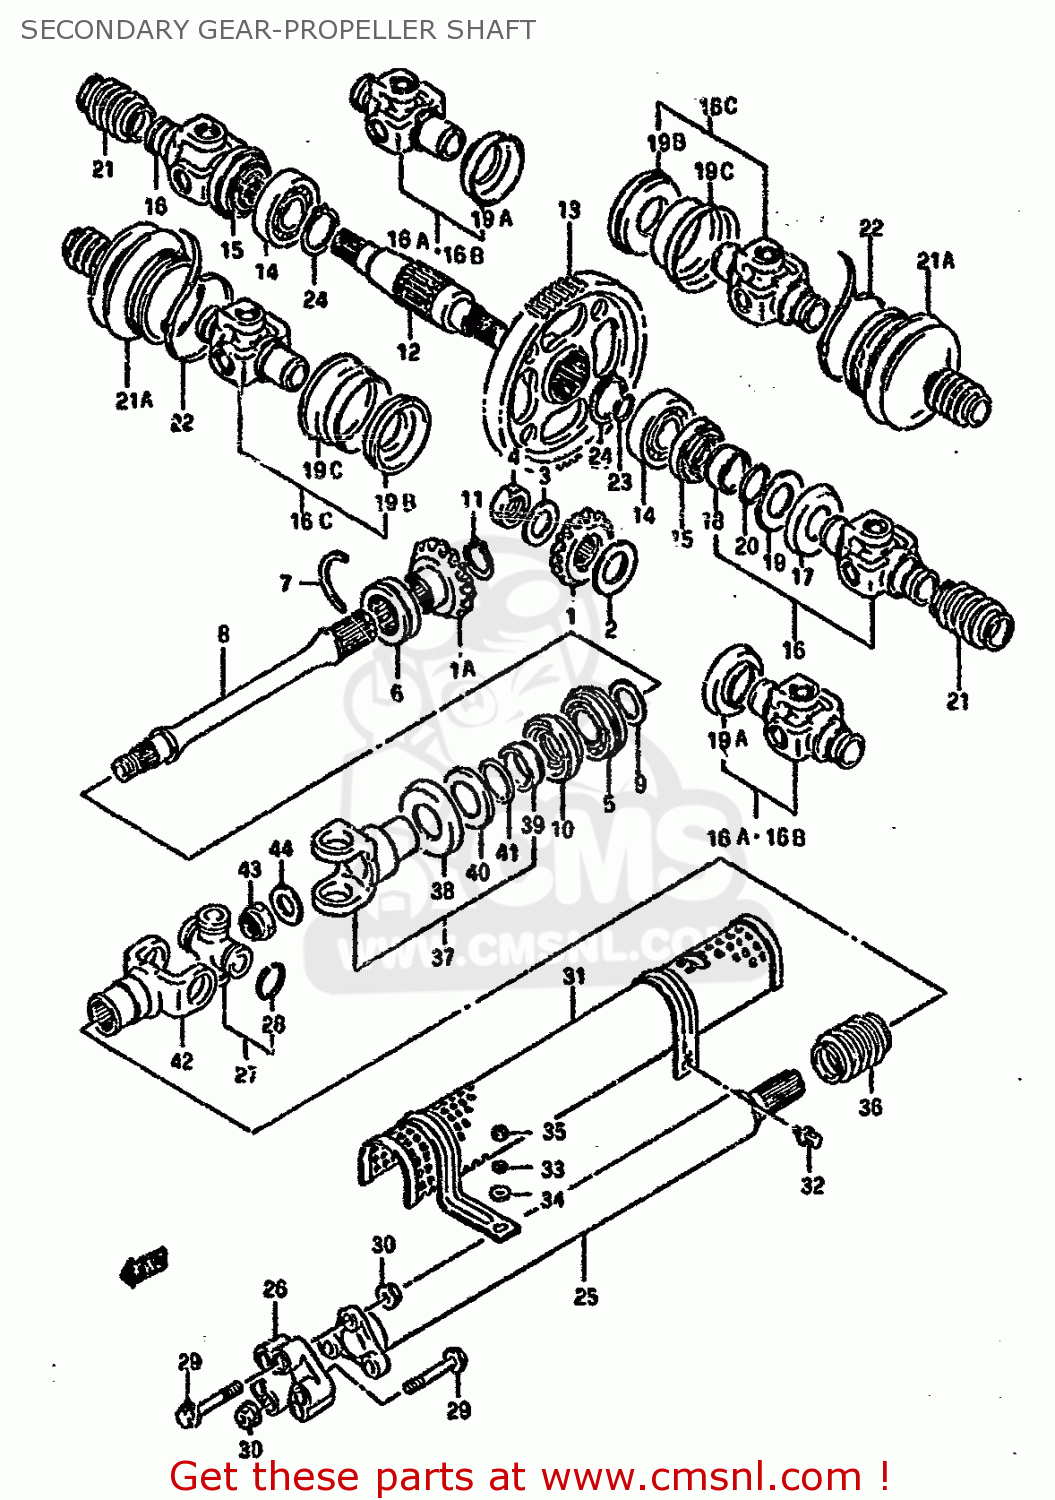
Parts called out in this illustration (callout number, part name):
1	GEAR,SECONDARY DRIVE BEVEL
1A	GEAR,2NDRY DRIVEN BEVEL
2	SHIM,SECONDARY DRIVE
3	WASHER
4	NUT
5	BALL BEARING 25X52X21
6	ROLLER BEARING (30X50X1
7	C RING
8	SHAFT,SECONDARY DRIVEN OUTPUT
9	SHIM
10	SEAL,OIL(34X52X9)
11	CIRCLIP
12	SHAFT,RR FINAL DRIVEN
13	GEAR,FINAL DRIVEN
14	BEARING(25X62X17)
15	SEAL,OIL(34X52X9)
16	JOINT,RR FINAL OUTPUT
16A	JOINT,REAR FINAL OUTPUT
16B	JOINT,RR FINAL OUTPUT
16C	JOINT,RR.F.OUT
17	WASHER
18	COLLAR,OUTPUT OIL SEAL
19	PLATE,OUTPUT YOKE OIL SEAL
19A	PLATE,OUTPUT OIL SEAL
19B	COVER,OUTPUT OIL SEAL
19C	COVER,UNIVERSAL JOINT
20	O RING(D:1,ID:28)
21	BOOT,PROPELLER SHAFT
21A	BOOT,UNIVERSAL JOINT
22	CLAMP,BOOT
23	RING
24	CIRCLIP
25	SHAFT,PROPELLER
26	COUPLING,PROPELLER SHAFT
27	JOINT,UNIVERSAL
28	RING,SNAP
29	BOLT
30	NUT
31	PROTECTOR,PROPELLER SHAFT
32	BOLT
33	WASHER,LOCK
34	WASHER
35	NUT
36	BOOT,PROPELLER SHAFT
37	YOKE COMP,FRONT DRIVE,OUTER
38	WASHER
39	COLLAR,OUTPUT OIL SEAL
40	PLATE,OUTPUT YOKE OIL SEAL
41	O RING(D:1,ID:28)
42	YOKE,PROP SHAFT JOINT
43	NUT
44	WASHER(16X30X3)
